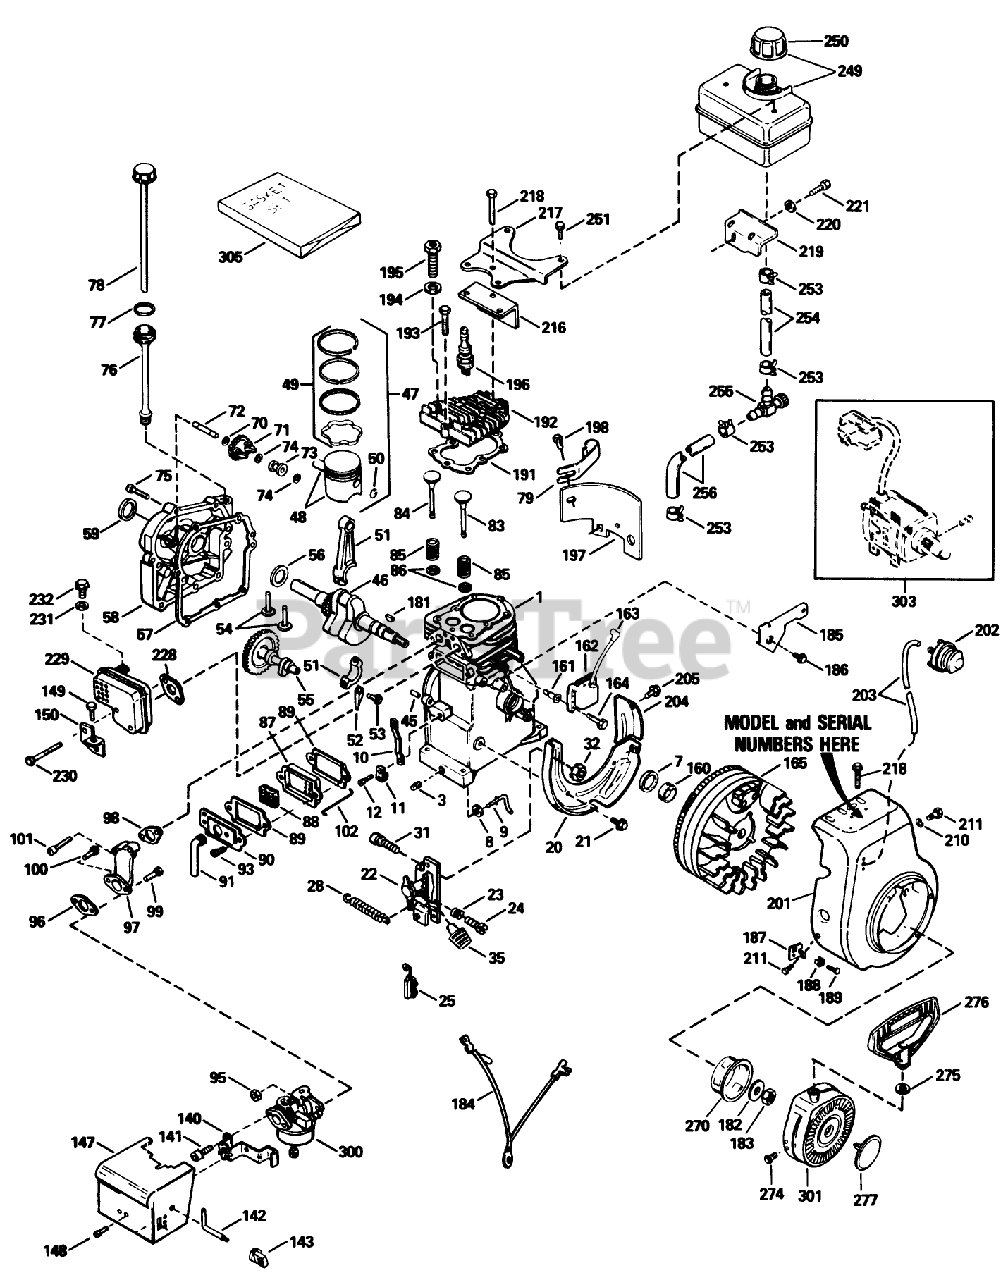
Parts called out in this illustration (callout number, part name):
1	Cylinder Assembly (Incl. Ref. #3, 7 45)
3	Plug-Drain, Oil (SQH 1/4-18)
7	Seal-Oil
8	Washer-Flat
9	Rod-Governor
10	Lever-Governor
11	Clamp-Lever, Governor
12	Screw
20	Baffle-Blower Housing
21	Screw (1/4-20x19/32)
22	Control Assembly, Speed (Incl. Ref. #155 thru 158 160)
23	Spring-Compression
24	Screw
25	Terminal
28	Spring-Extension
31	Screw
32	Nut-Lock
35	Knob-Control
45	Pin-Dowel
46	Crankshaft ASM
47	Piston, Pin Ring Assy., (Incl. Ref. #15 16) (Std.)
47	Piston, Pin Ring Assy., (Incl. Ref. #15 16) (.010 Oversize)
47	Piston, Pin Ring Assy., (Incl. Ref. #15 16) (.020 Oversize)
48	Piston Pin Assy. (Incl. Ref. #16) (Std.)
48	Piston Pin Assy., (Incl. Ref. #16) (.010 Oversize)
48	Piston Pin Assy. (Incl. Ref. #16) (.020 Oversize)
49	Ring Set-Piston Std.
49	Ring Set-Piston .010 oversize
49	Ring Set-Piston .020 oversize
50	Ring-Retaining, Piston Pin
51	Rod Assembly, Connecting (Incl. Nos. 17 18)
52	Dipper-Oil
53	Bolt-Rod, Connecting
54	Lifter-Valve
55	Camshaft
56	Washer-Thrust
57	Gasket-Cover, Cylinder
58	Cover-Cylinder (Incl. Ref. #59 72)
59	Seal-Oil
70	Washer
71	Governor Gear ASM
72	Shaft-Governor
73	Spool-Governor
74	Ring-Retaining
75	Screw (1/4-20 x 1-1/4)
76	Tube-Fill, Oil
77	O-Ring
78	Dipstick
79	Clip-Tube, Fill
83	Valve, Exhaust (Std.)(Incl. No. 40)
83	Valve, Intake (1/32" oversize)(Incl. No. 40)
84	Valve-Intake Standard (Incl. Ref. #151)
84	Valve-Intake 1/32" oversize (Incl. Ref. #151)
85	Spring-Valve
86	Cap-Valve, Spring
87	Body-Breather
88	Element-Breather
89	Gasket-Cover, Valve
90	Cover-Breather
91	Tube-Breather
93	Screw
95	Nut and Lock Washer (1/4-28)
96	Gasket
97	Pipe-Intake
98	Gasket-Intake
100	Screw (1/4-28 x 1-11/16)
101	Screw (1/4-20 x 1-19/32)
102	Link-Governor to Throttle
140	Bracket-Choke
141	Screw (10-32 x 1/2)
142	Rod-Choke
143	Knob-Control
147	Cover-Carburetor
148	Screw (8-32 X 5/16)
149	Screw (10-24 x 3/8)
150	Bracket-Cover, Carburetor
160	Spacer
162	Solid State
163	Cover-Spark Plug
164	Screw
165	CLAMP
181	Key-Flywheel
182	Washer-Belleville
183	Nut-Flywheel
184	Wire-Ground
185	Bracket-Hold Down
186	Screw (10-24 x 9/16)
187	Bracket
188	Grommet
189	Screw (8-32 x 3/8)
191	Gasket-Cylinder Head
192	Head-Cylinder (Incl. Ref. #218)
193	Screw (5/16-18x1-1/2)
194	Washer-Flat
195	Screw ( 5/16-18 x 1-1/2)
196	Spark Plug-Resistor (R J19 L M)
197	Extension-Blower
198	Screw
201	Housing-Blower
202	Primer-Asm
203	Line-Primer
204	Baffle-Extension
205	Screw-Hex Washer Hd.
210	Washer
211	Screw
216	Baffle-Heat
217	Plate-Fuel Tank
218	Screw (5/16-18 X 2)
219	Bracket-Fuel Tank
220	Washer
221	Screw Assembly
228	Gasket-Exhaust
229	MANUAL
230	Screw-Fil. Hd.
231	Washer
232	Screw
249	Tank Assembly-Fuel (Incl. Ref. #250 253)
250	Cap-Fuel
251	Screw (1/4-15x7/8)
253	Clamp-Line, Fuel
254	Line-Fuel (8.62)
255	Valve-Shut Off
256	Line-Fuel
270	Cup-Starter
274	Screw, Hex Hd.
275	Washer
276	Handle-Starter, Mitten Grip
277	Plug Starter
300	Carburetor (Incl. Ref. #96)
301	Rewind Starter
303	Electric Starter Kit 33290C (Optional) Sold as Accessory
305	Gasket Set (Incl.Items Marked *)
